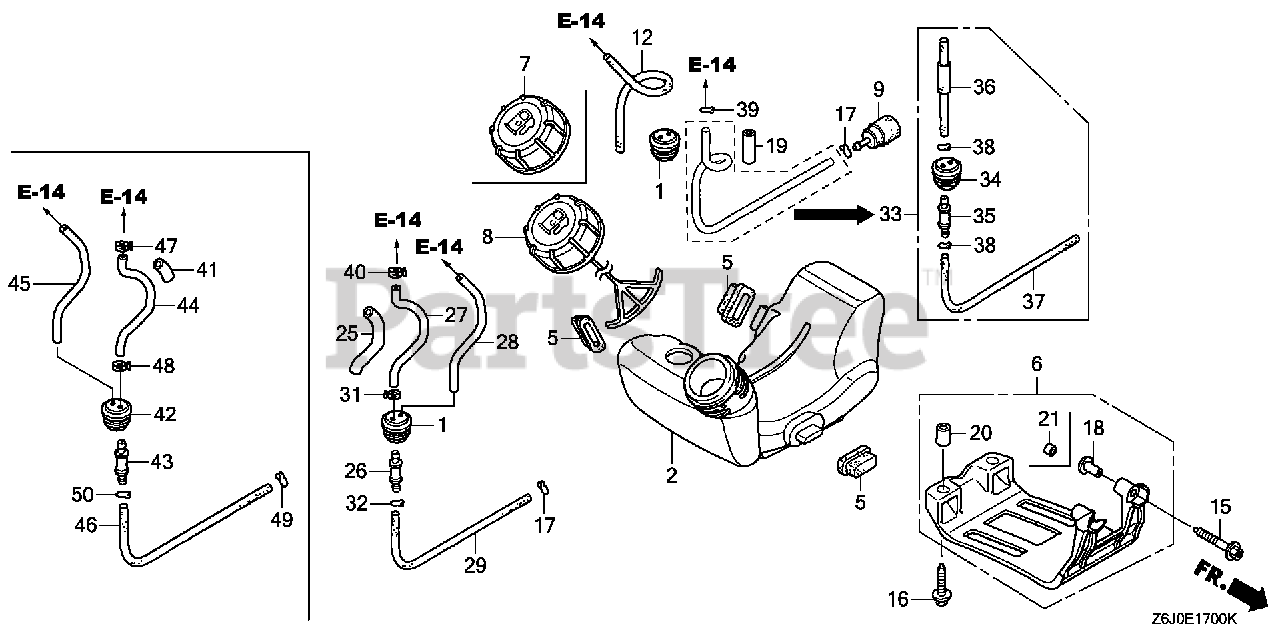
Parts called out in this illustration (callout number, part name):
1	GROMMET, FUEL TUBE
2	TANK, FUEL
2	TANK, FUEL (FOR U.S.A.)
5	RUBBER, TANK MOUNTING
8	CAP ASSY., FUEL TANK
9	FILTER, FUEL
12	TUBE, FUEL RETURN
17	CLIP, TUBE
19	PROTECTOR, TUBE
25	PROTECTOR, TUBE
26	JOINT, FUEL TANK
27	TUBE, FUEL
28	TUBE, FUEL RETURN
29	TUBE A, FUEL
30	CLAMP, TUBE
31	CLAMP, TUBE
32	CLIP, TUBE
33	GROMMET ASSY., FUEL TANK
34	GROMMET, FUEL TUBE
35	FITTING
36	TUBE, FUEL FEED
37	TUBE A, FUEL
38	CLIP, TUBE
39	CLIP, TUBE
40	CLAMP, TUBE
41	PROTECTOR, TUBE
42	GROMMET, FUEL TUBE
43	JOINT, FUEL TANK
44	TUBE, FUEL
45	TUBE, FUEL RETURN
46	TUBE A, FUEL
47	CLAMP, TUBE (D5.5)
48	CLAMP, TUBE (D5.5)
49	CLIP, TUBE (B1 5)
50	CLIP, TUBE (B1 5)
